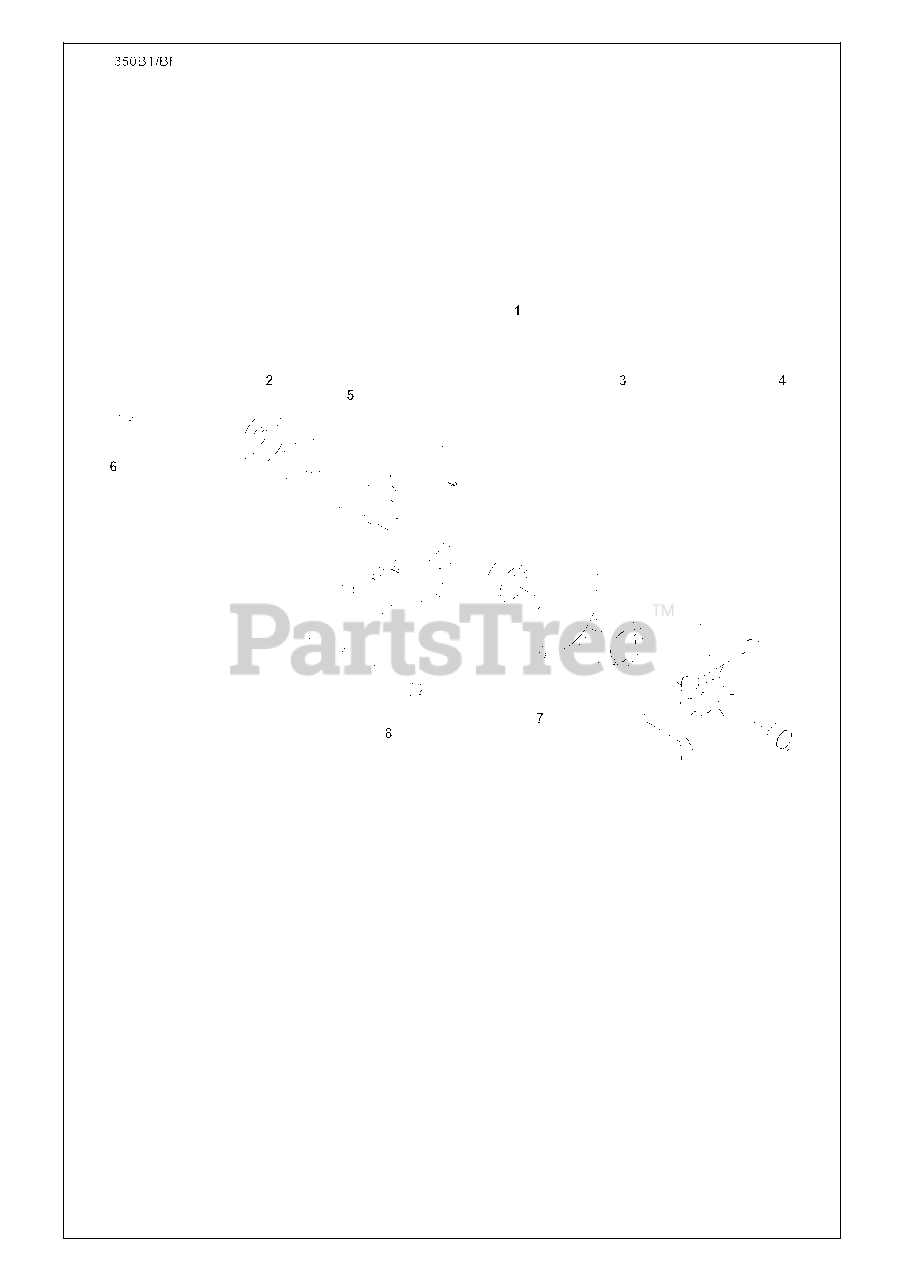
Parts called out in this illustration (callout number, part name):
3	BEARING
6	BOLT
8	BOLT
